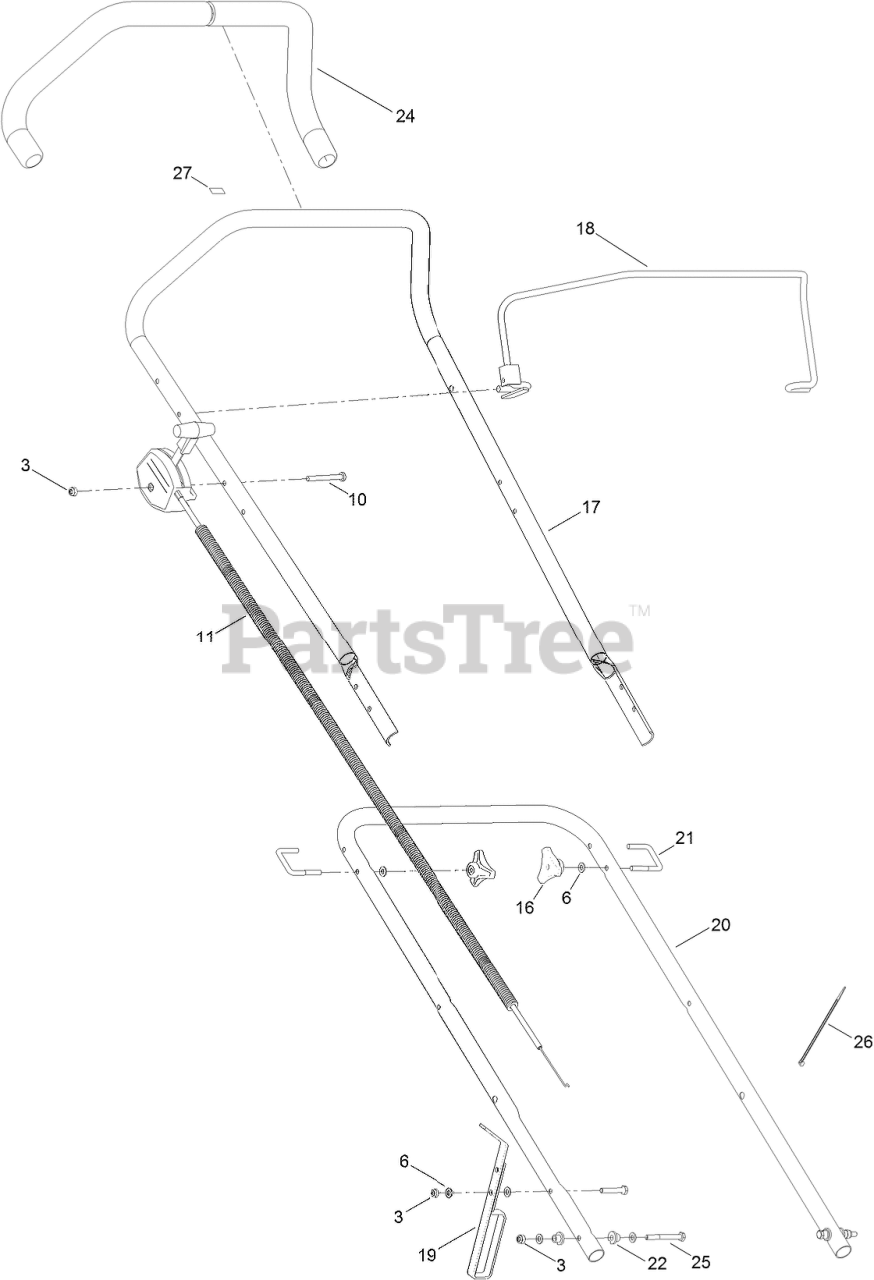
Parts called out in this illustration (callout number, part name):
3	NUT-NYLOC
6	WASHER-PLAIN
10	SETSCREW
11	THROTTLE CONTROL ASM
16	HANDWHEEL
17	HANDLE-UPPER
18	ARM-BAIL
19	FOOTSTOP
20	HANDLE-LOWER
21	BOLT-U
22	SPACER-HANDLE
24	GRIP-HANDLE
25	BOLT-HEX
26	TIE-CABLE
27	DECAL-STOP
